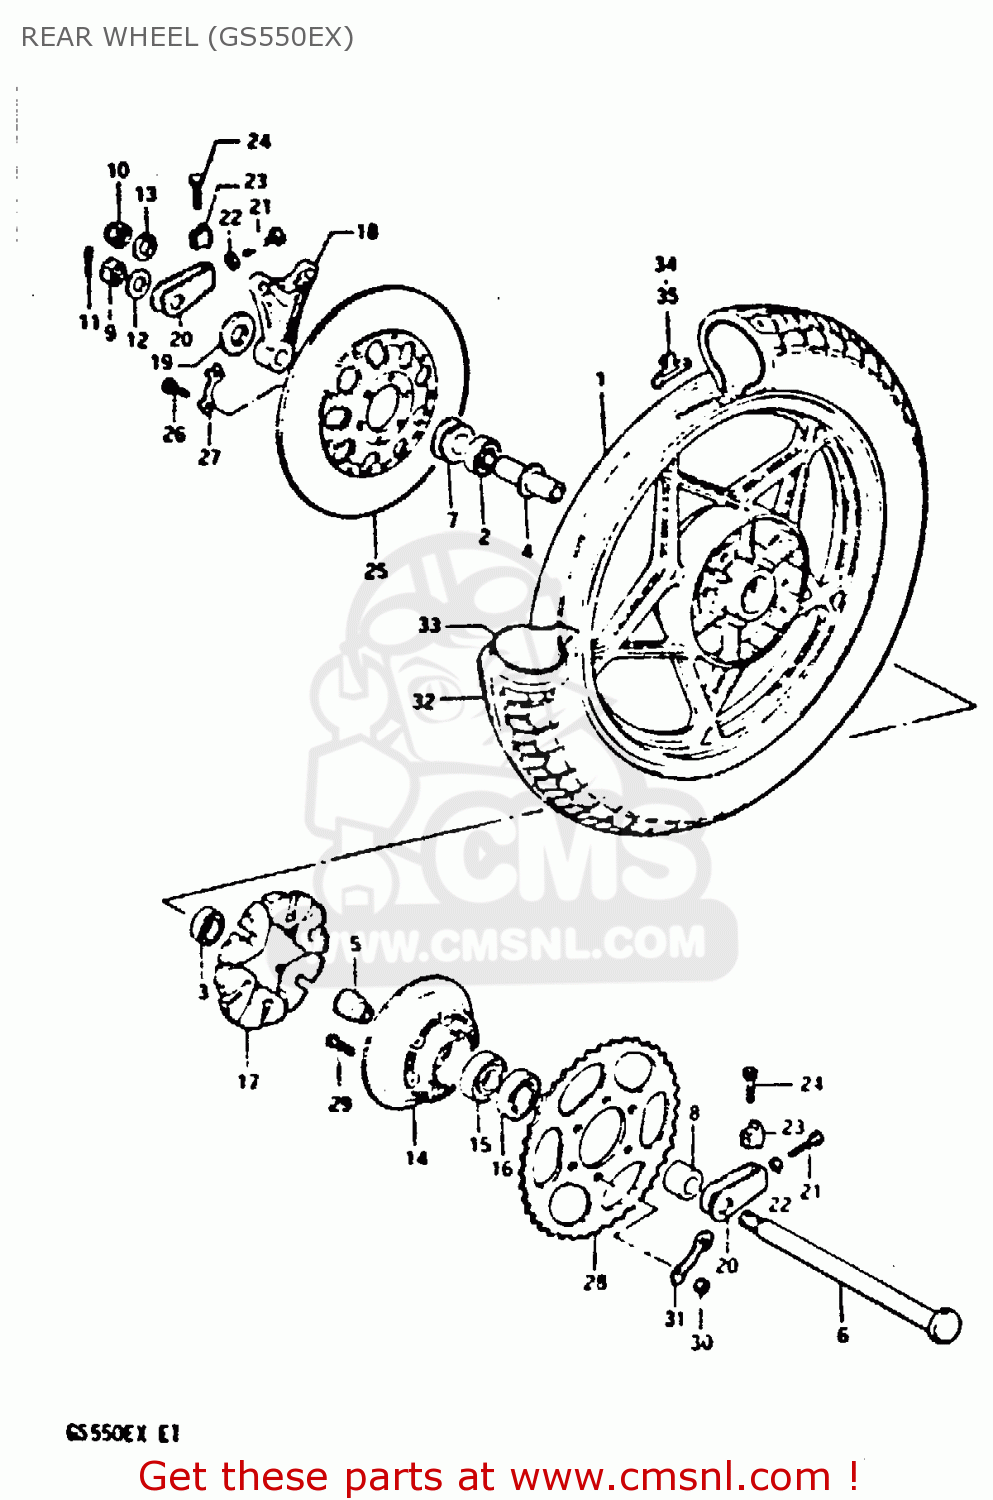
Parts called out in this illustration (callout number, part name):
1	WHEEL, REAR
2	BEARING, RH
3	BEARING
4	SPACER,REAR HUB BEARING
5	RETAINER,REAR SPROCKET D
6	AXLE,REAR
7	SPACER,REAR AXLE
8	SPACER (17X33X21.1)
9	NUT
11	PIN,COTTER
12	WASHER (17X30X3.2)
14	DRUM,REAR SPROCKET MOUNT
15	BEARING
16	SEAL,OIL(33X62X7)
17	ABSORBER,REAR HUB SHOCK
18	BRACKET,RR,CALIPER
19	SPACER,REAR CARIPER BRACKET
20	ADJUSTER,CHAIN
21	BOLT
22	NUT
23	SUPPORTER,CHAIN ADJUST
24	BOLT
25	DISC,BRAKE
26	BOLT(8X30)
27	WASHER
28	SPROCKET,RR
29	BOLT
30	NUT
31	WASHER
32	TIRE
33	TUBE ASSEMBLY,WHEEL,INNER
34	BALANCER,WHEEL
35	BALANCER,WHEEL
